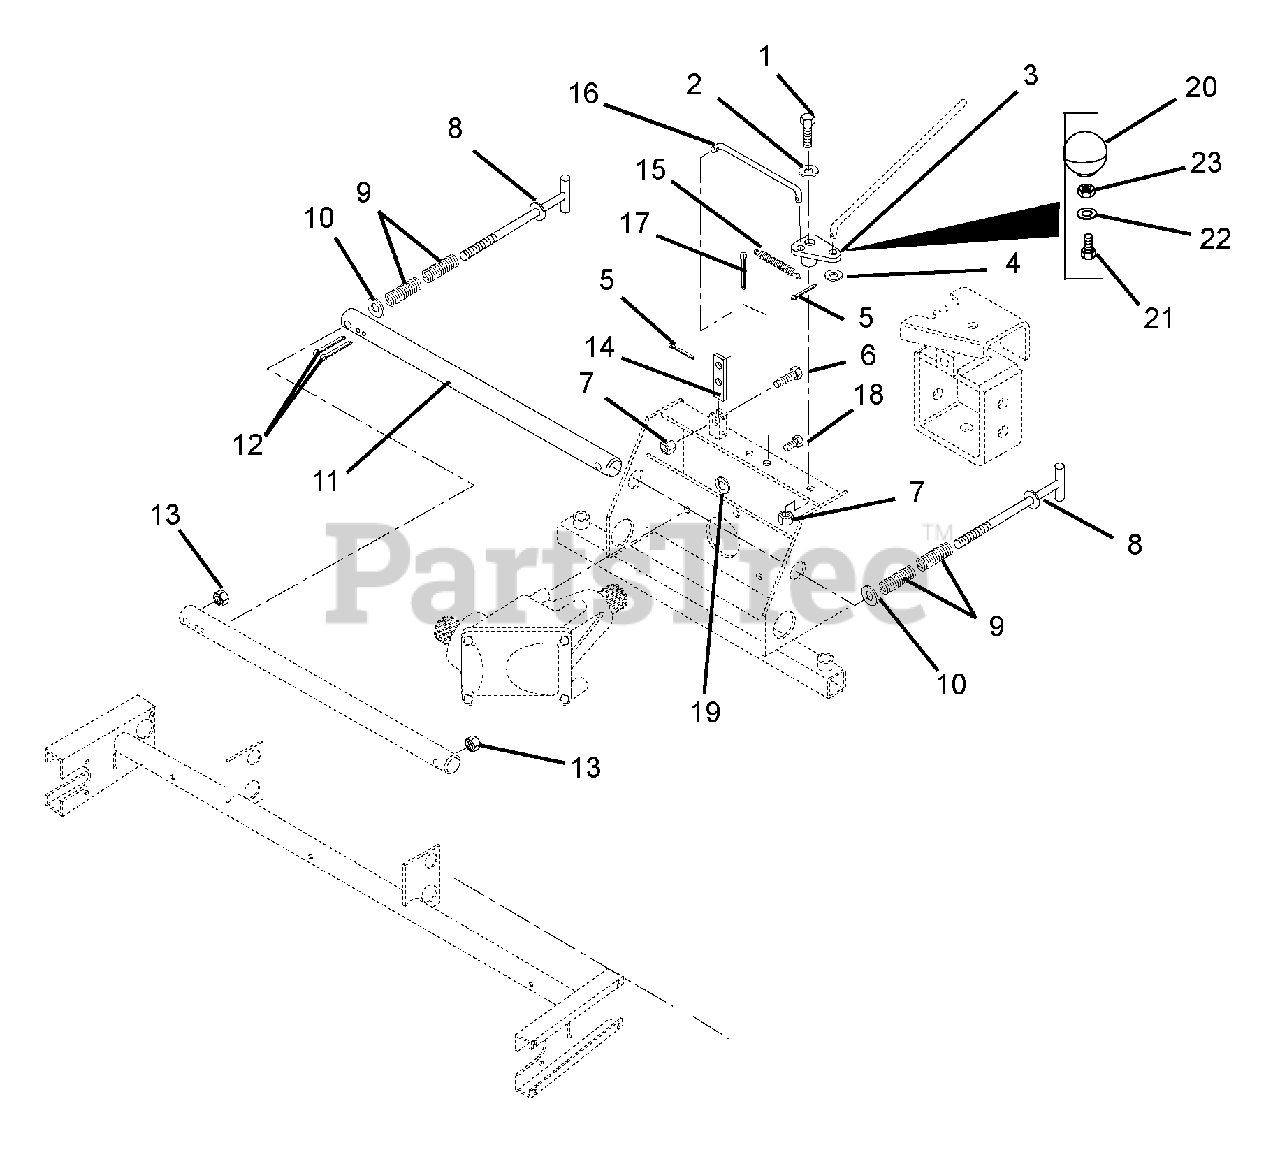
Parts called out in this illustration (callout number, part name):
1	Bolt-Hex .38-16 x 2.25 Grade 5
2	Washer-Flat-Steel .406 x .812 x .065
3	Weldment-Bracket
4	Washer-Flat-Steel .281 x .62 x .065
5	Pin-Cotter.125 x.750
6	Bolt-Hex.38-16 x 1.50 Grade 5
7	Nut-Locking-Center.31-18
8	Weldment-Rod
9	Spring-Compression.125 x.78 x 1.00
10	Washer-Flat-Steel.563 x 1.38 x.109
11	Anchor, Adjustment
12	Pin-Cotter .125 x 1.50
13	Nut-Hex .50-13
14	Plate-Locking
15	Spring, Tension .075 x .75 x 2.25
16	Rod-Linkage
17	Pin-Cotter .375 x 1.375
18	Bolt, Hex .50-13 x 1.25 Grade 5
19	Washer, Locking .50 x .125 Regular
20	Knob
21	Bolt, Hex .31-18 x 1.25 Grade 5
22	Washer, Flat, Steel .323 x .625 x .062
23	Nut, Spin Lock, Flange .312-18
